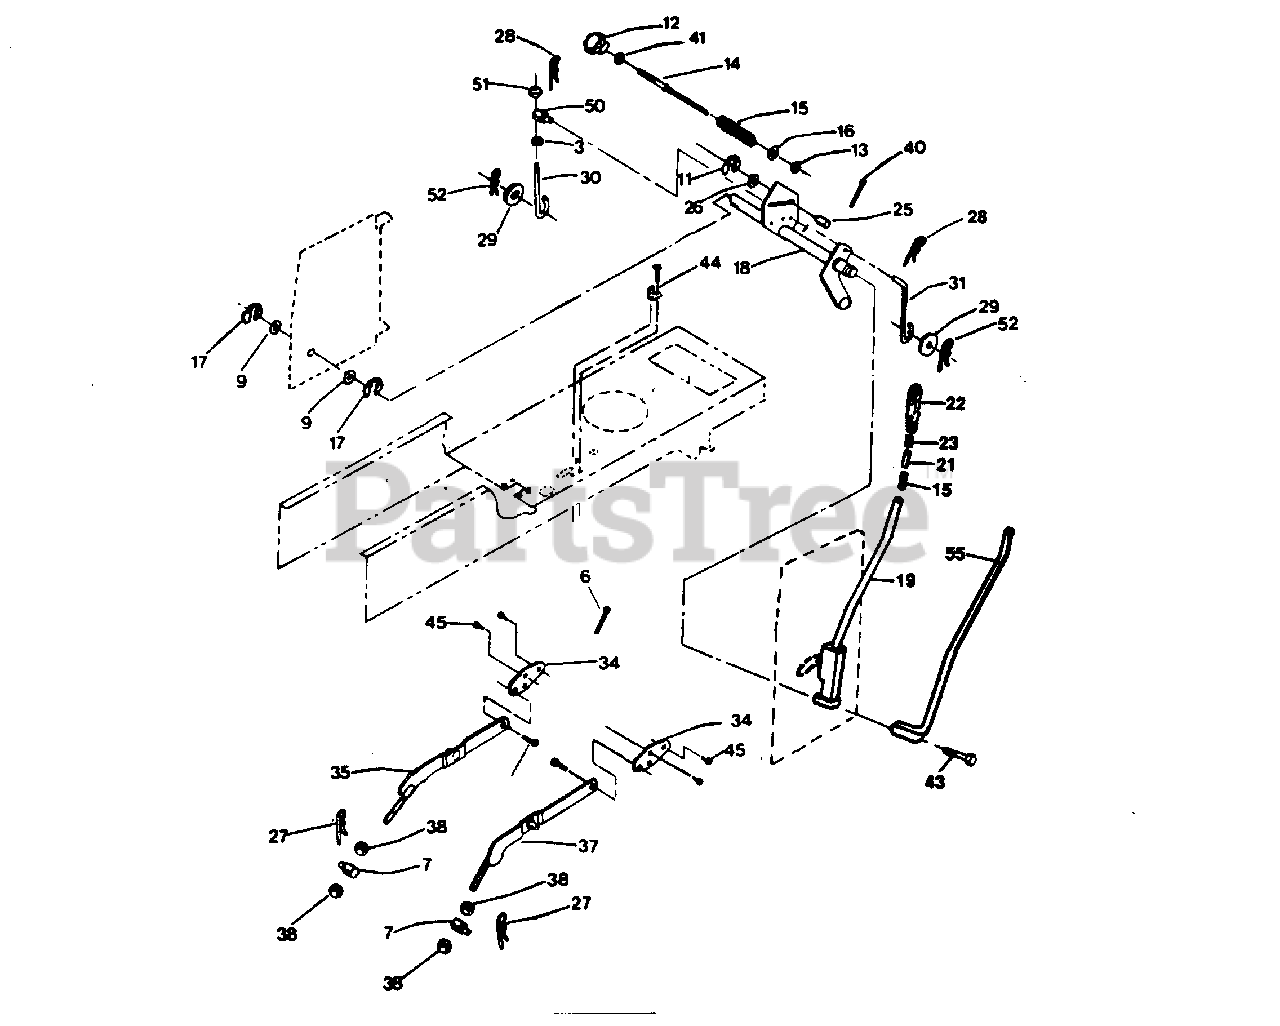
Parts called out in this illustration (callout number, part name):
1	Jam Locknut (AYP part number)
7	Lower Lift Trunnion (AYP part number)
9	Washer (AYP part number)
10	Bellcrank Bracket (AYP part number)
11	Klip Ring (AYP part number)
12	Lift Adjust Handle (AYP part number)
13	Special Nut (AYP part number)
14	Lift Adjust Rod (AYP part number)
15	Spring (AYP part number)
16	Washer (AYP part number)
17	E-Ring (AYP part number)
18	Lift Shaft (AYP part number)
19	Lift Lever (AYP part number)
20	Crownlock Nut
21	Lever Plunger (AYP part number)
22	Handle Grip (AYP part number)
23	Plunger Button (AYP part number)
25	Stop Depth Trunnion
26	Washer (AYP part number)
27	Spring Retainer (AYP part number)
28	Spring Retainer (AYP part number)
29	Washer (AYP part number)
30	Adjust Link Lift (AYP part number)
31	Lift Link (AYP part number)
32	Carriage Bolt 3/8-16 x 3/4 (AYP part number)
34	Suspension Bracket (AYP part number)
35	L.H. Arm Suspension (AYP part number)
37	R.H. Arm Suspension (AYP part number)
38	Fin. Hex Nut (AYP part number)
40	Cotter Pin (AYP part number)
41	Jam Hex Nut (AYP part number)
43	Hex Bolt (AYP part number)
44	Switch Bracket (AYP part number)
45	Tap Hex Screw (AYP part number)
50	Lift Trunnion (AYP part number)
51	Jam Crownlock Nut (AYP part number)
52	Retainer Spring (AYP part number)
53	Spring Washer (AYP part number)
54	Flange Locknut (AYP part number)
55	Lift Lever Rod Assembly (AYP part number)
